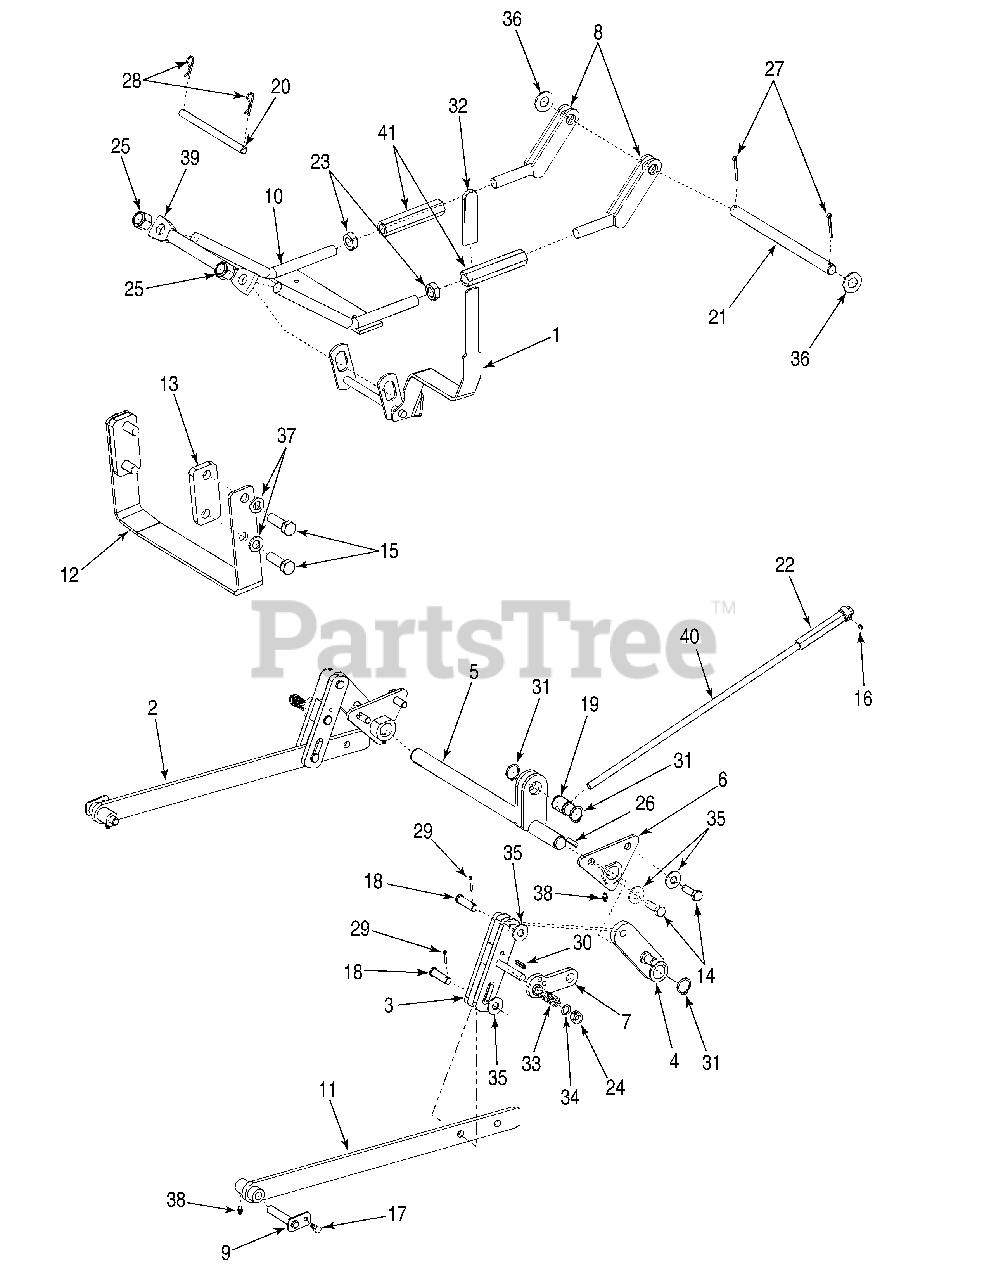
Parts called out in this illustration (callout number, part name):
1	Shaft, Tension
2	Arm, Lift RH
4	Arm, Rock Shaft Lift
6	Bracket, Rock Shaft Mounting
7	Latch, Lift Hanger
8	Rod, Lower Front Hanger
9	Pin, Deck Lift
10	Hanger, Top Front
11	Arm, Lift LH
12	Bracket, Front Upstop
13	Bracket, Front Upstop Spacer
14	Screw, Hx Cap, M12-1.75 x 35 Gr8
15	Screw, Hx Cap, M16-2.0 x 50 Gr8
16	Screw, Socket Set, 1/4-20 x .38
17	Screw, Hex Cap, M8-1.25 x 14 Gr8
19	Pin, Pivot Ferrule
20	Pin, Front Hanger
21	Pin, Front Hanger
22	Sleeve, Lift Rod (Ajustment)
23	Nut, Hex Jam, 3/4-10 Gr5
24	Nut, Hex Center Lock 1/2-13 GrB
25	Nut, Hex Lock, 3/4-10 GrC
26	Key, Square, 1/4 x 1.0
27	Pin, Cotter, 3/16 x 1.5 Lg
28	Pin, Internal Cotter
29	Pin, Cotter, .125 x .75
30	Pin, Roll, .25 x 1.0
31	Ring, Snap, 1.0 Dia Shaft
32	Grip, Black
33	Spring, Compression, .57 x 2.09
34	Washer, Flat, .51 x .75 x .033
35	Washer, Flat, .5 x 1.25 x .10
36	Washer, Flat, .76 x 1.5 x .12
37	Washer, Flat, .64 x 1.12 x .125
38	Fitting, Lube
39	Rod, Front Hanger Pivot
40	Rod, Deck Height Adjust
41	Rod, Deck Hanger Adjust
